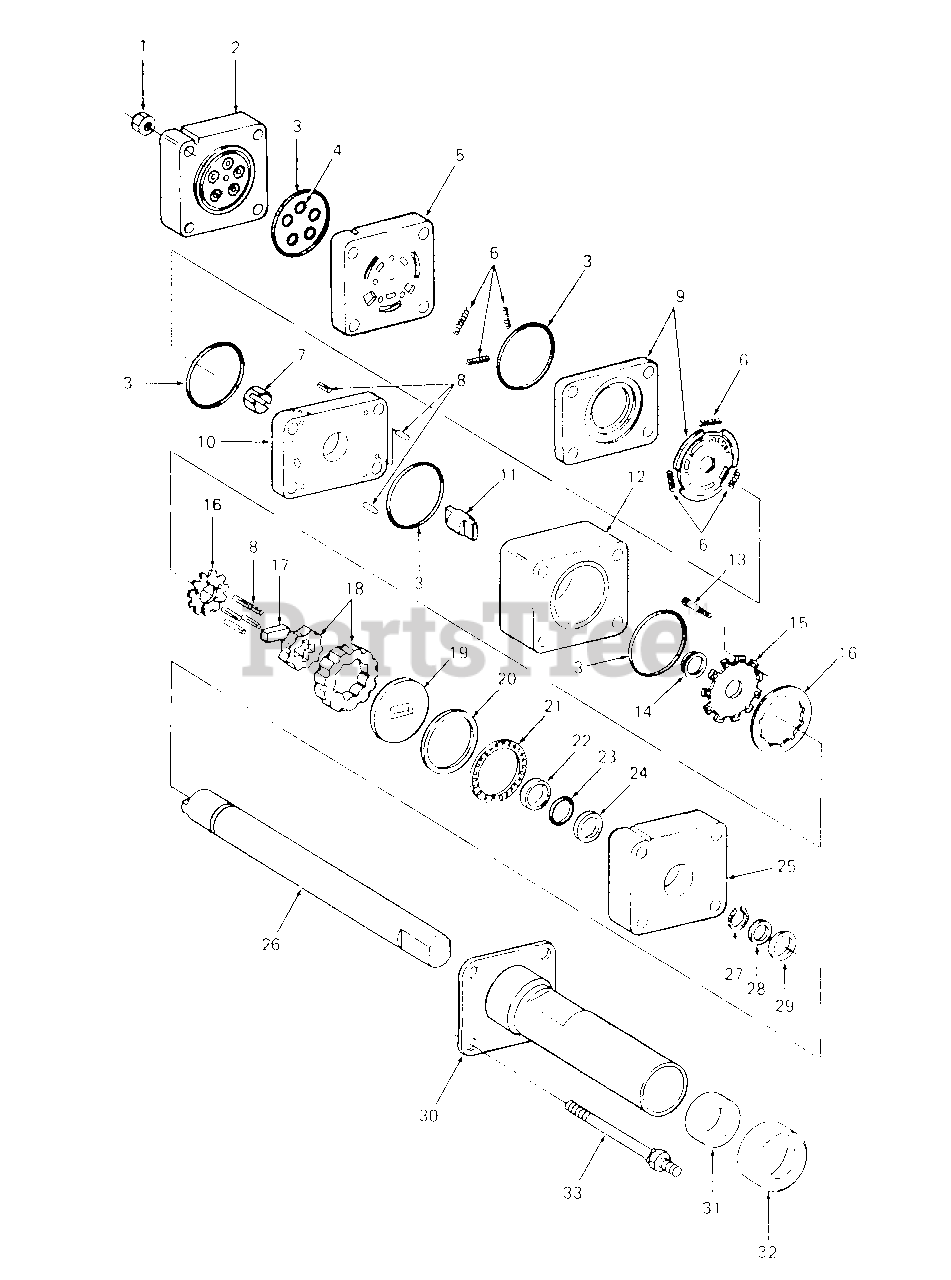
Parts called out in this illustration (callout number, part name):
1	Nut, Hex, 5/16-24
2	Power Cover & Check Valve Assy
3	Ring, Seal
4	O-Ring
5	Manifold, Port
7	Drive Assy, Hex
8	Roller Kit, Needle
9	Valve & Ring Assy
10	Manifold, Isolation
12	Ring, Metering
14	Seal
15	Cover, Commutator
16	Commutator & Ring Assy
17	Spacer, Drive Link
21	Bearing, Thrust
22	Seal, Face
23	Ring, Back-up
24	Seal, Spacer
25	Plate, Upper Cover
26	Input Shaft Assy
27	Ring, Retaining
29	Plate, Retaining
30	Upper Cover & Tube Assy w/Flat
31	Bearing, Column
32	Dust Seal, Column
33	Bolt, Special
